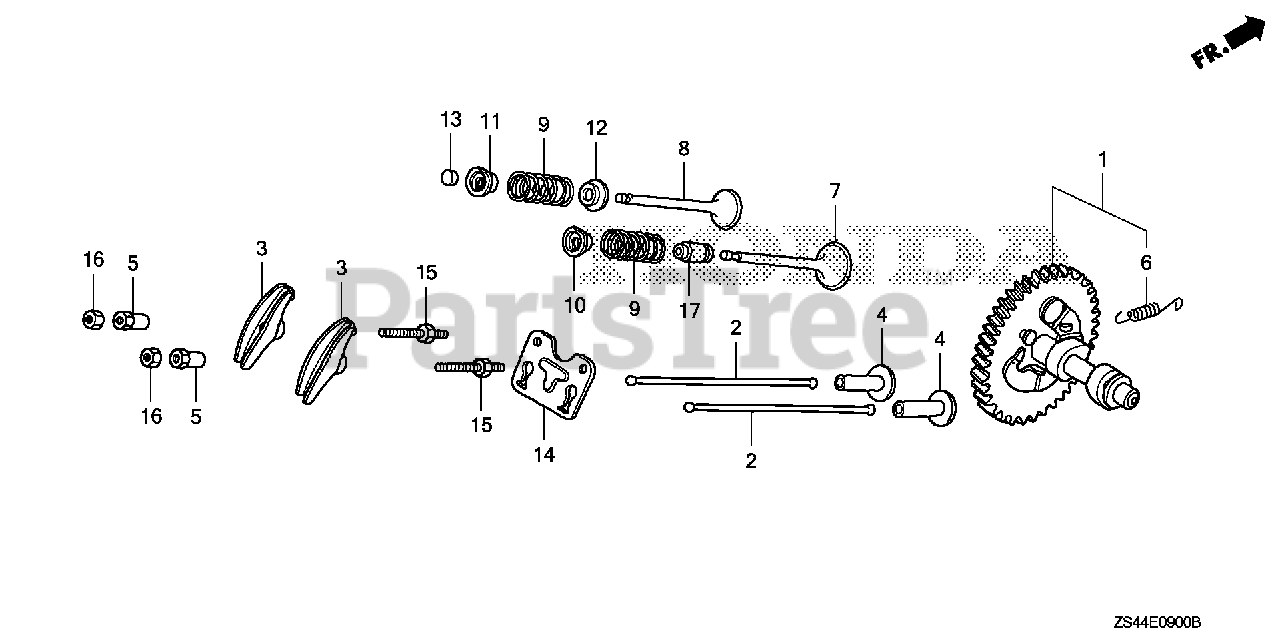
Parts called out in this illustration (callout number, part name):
1	CAMSHAFT ASSY.
3	ARM, VALVE ROCKER
4	LIFTER, VALVE
5	PIVOT, ROCKER ARM
6	SPRING, WEIGHT RETURN
7	VALVE, IN.
8	VALVE, EX. (STELLITE)
9	SPRING, VALVE
10	RETAINER, IN. VALVE SPRING
11	RETAINER, EX. VALVE SPRING
12	SEAT, VALVE SPRING
13	ROTATOR, VALVE
14	GUIDE, PUSH ROD
15	BOLT, PIVOT (8MM)
16	NUT, PIVOT ADJUSTING
17	SEAL, VALVE STEM
